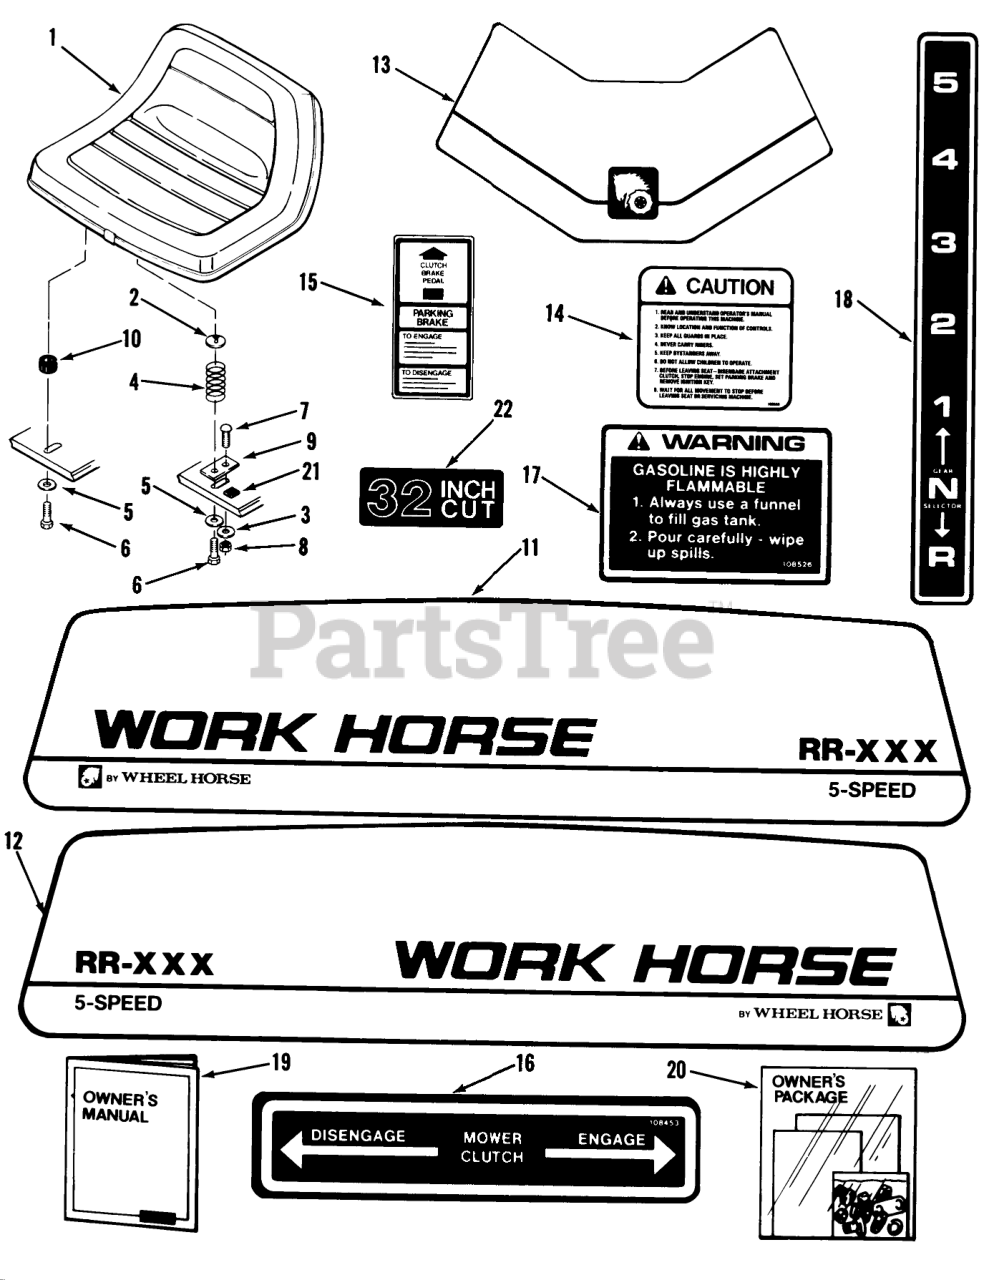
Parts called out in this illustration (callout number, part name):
5	WASHER 5/16 SAE
7	CARRIAGE BOLT -4
19	Owner-s Manual (Rider)
20	New Rider Loose Parts Pkg RR-832
20	New Rider Loose Parts Pkg RR-532
21	BUMPER
